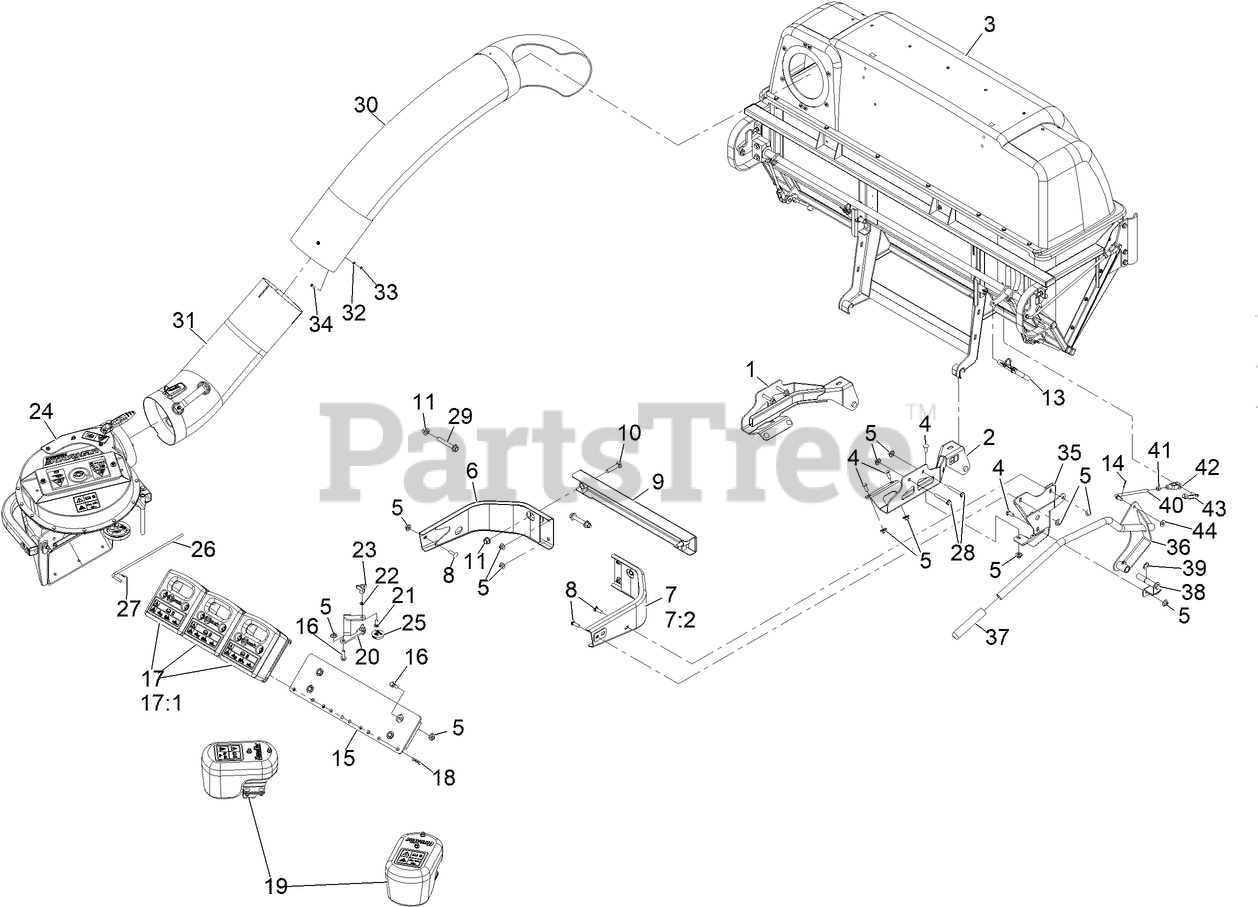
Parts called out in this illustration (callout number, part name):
1	ASM, BAGGER MOUNT W/ DECAL, RT
2	ASM, BAGGER MOUNT W/ DECAL, LT
3	Asm, Hopper
4	SCREW-CARR
5	Nut-Nyloc 3/8-16 Flg
6	BUMPER-RH
7	LH BUMPER ASM
7:2	DECAL-WARNING
8	Bolt-Carriage 3/8-16 X 1 1/4
9	MOUNT-BAGGER, UPPER
10	SCREW-CARR
11	Nut-Lock 1/2-13
13	PIN-MOUNT, BAGGER
14	PIN-COTTER
15	WLD, MOUNT TOEBOARD WEIGHT
16	SCREW-HHF
17	ASM,CAST WEIGHT
17:1	DECAL-WARNING WEIGHT
18	PIN-HAIR
19	ASM-Caster Weight
20	BRACKET,BELT COVER
21	BOLT-CARR
22	RING-RETAINING, BOLT
23	KNOB-3 PRONG
24	ASM, BLOWER LARGE - SVC ONLY
25	PLUG, BLACK NYLON 1.75
26	PIN,CHUTE PIVOT
27	PIN-COTTER
28	SCREW-HFH
29	SCREW-HHF
30	TUBE-UPPER
31	ASM, Lower Chute
32	WASHER-FLAT
33	NUT-LOCK, NI
34	SCREW-HWH
35	WELD, MOUNT PLATE
36	WLD,DUMP HANDLE
37	HANDLE-GRIP
38	PIN-HANDLE
40	LINK-HANDLE
41	NUT-HEX
42	YOKE-LINKAGE, BRAKE
43	PIN-SPRING, CLEVIS
44	WASHER-FLAT
